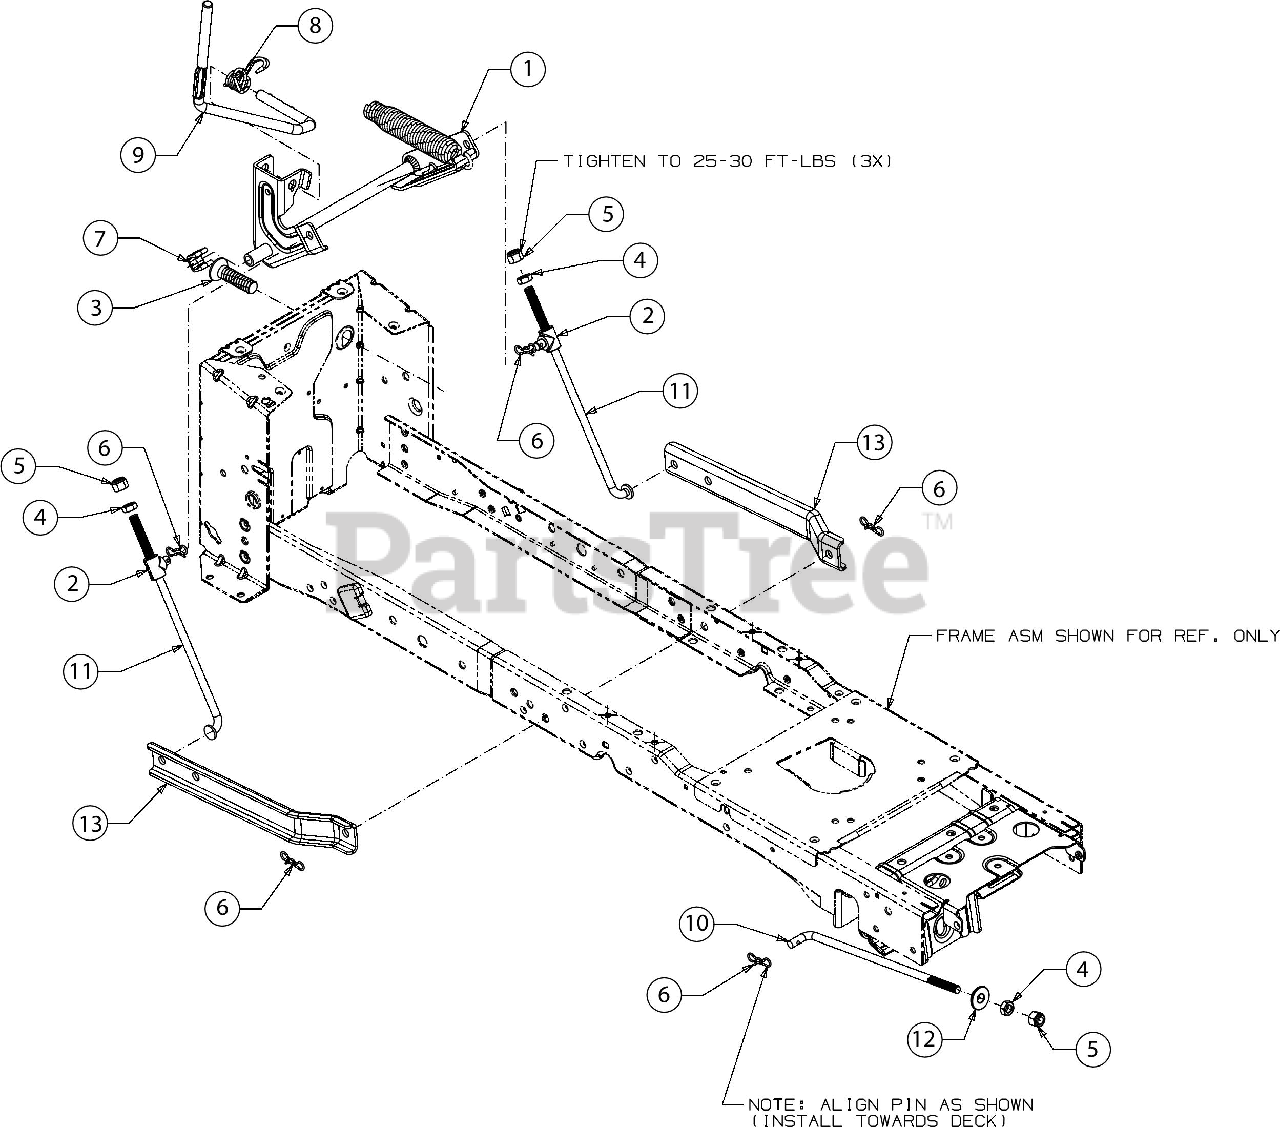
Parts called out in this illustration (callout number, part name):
1	LIFT SHAFT ASSEMBLY
2	LIFT ROD FERRULE
3	LIFT SPRING INSERT
4	HEX NUT
5	HEX LOCK NUT NYLON
6	BOW TIE COTTER PIN
7	SPACER-LIFT SHAFT
8	TORSION SPRING
9	DECK LIFT HANDLE
10	DECK FRONT LIFT ROD
11	ADJUSTMENT LIFT ROD
12	LIFT PIVOT CUP
